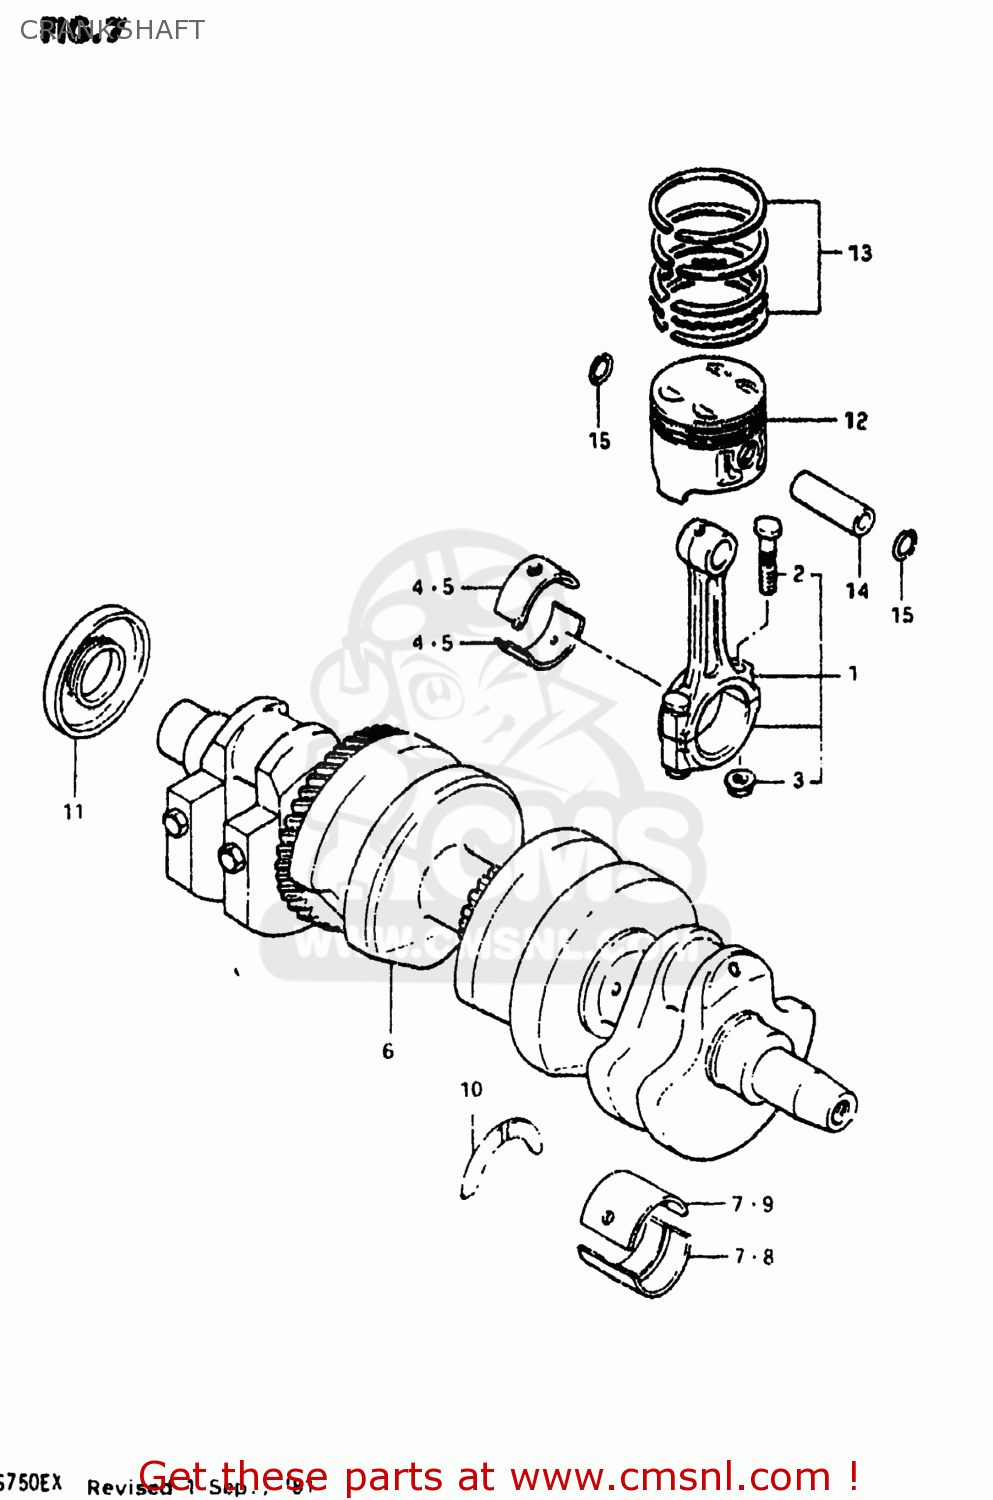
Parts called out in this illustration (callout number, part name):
1	CONNECTING ROD ASSEMBLY
2	BOLT,CONNECTING ROD
3	NUT
4	BEARING,CRANK PIN
5	BEARING,CRANK PIN
6	CRANKSHAFT
7	METAL CRANKSHAFT
8	METAL CRANKSHAFT
9	METAL CRANKSHAFT
10	PLATE,CRANK THRUST
11	OIL SEAL
12	PISTON
13	RING SET,PISTON
14	PIN,PISTON (18MM)
15	CIRCLIP
